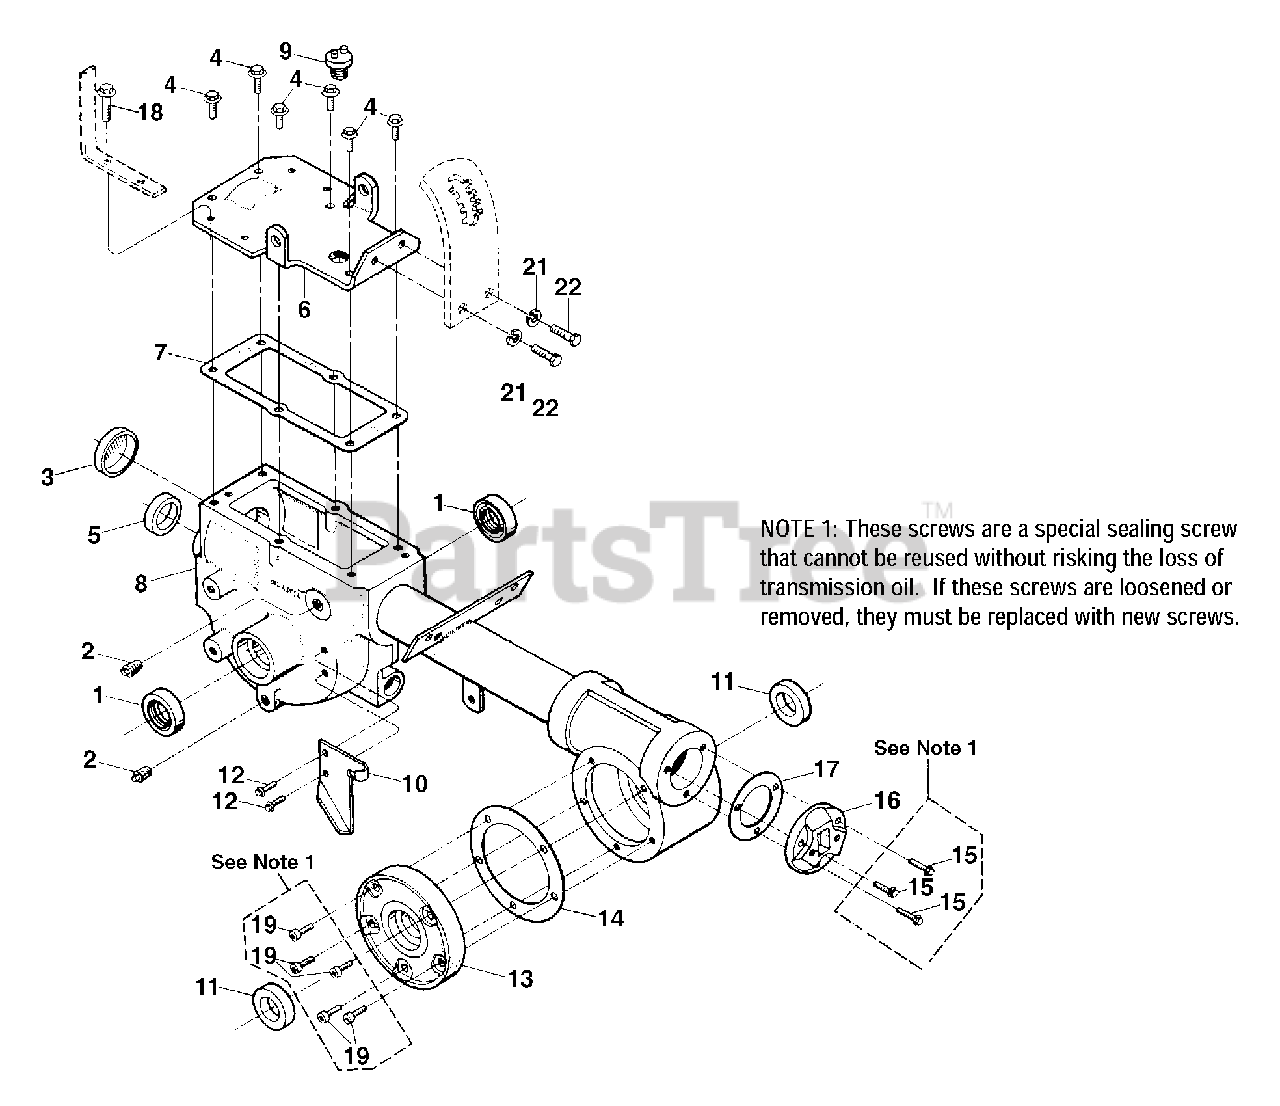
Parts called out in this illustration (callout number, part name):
1	Oil Seal (Double Lip), Wheel Shaft
2	Pipe Plug, 1/4,
3	Seal, Transmission Bore
4	Hex Flange Screw, 5/16-18 x 3/4
5	Oil Seal, Input Pinion Shaft
6	Transmission Cover
7	Gasket, Transmission Top Cover
8	Transmission Case Assy.
10	Mounting Plate, Wheel Clutch Cable
11	Oil Seal, Tiller Shaft
12	Hex Flange Screw, 5/16-18 x 5/8
13	Tiller Housing Cover, left side
14	Gasket, Tiller Housing Cover, .010" (fits all covers)
15	Screw Kit:
16	Rear Bearing Cap
17	Gasket, Rear Bearing Cap, .010" Thick
18	Hex Flange Screw, 5/16-18 x 1
19	Screw Kit:
21	Lockwasher, 3/8
22	Hex Hd. Screw, 3/8-16 x 3/4
